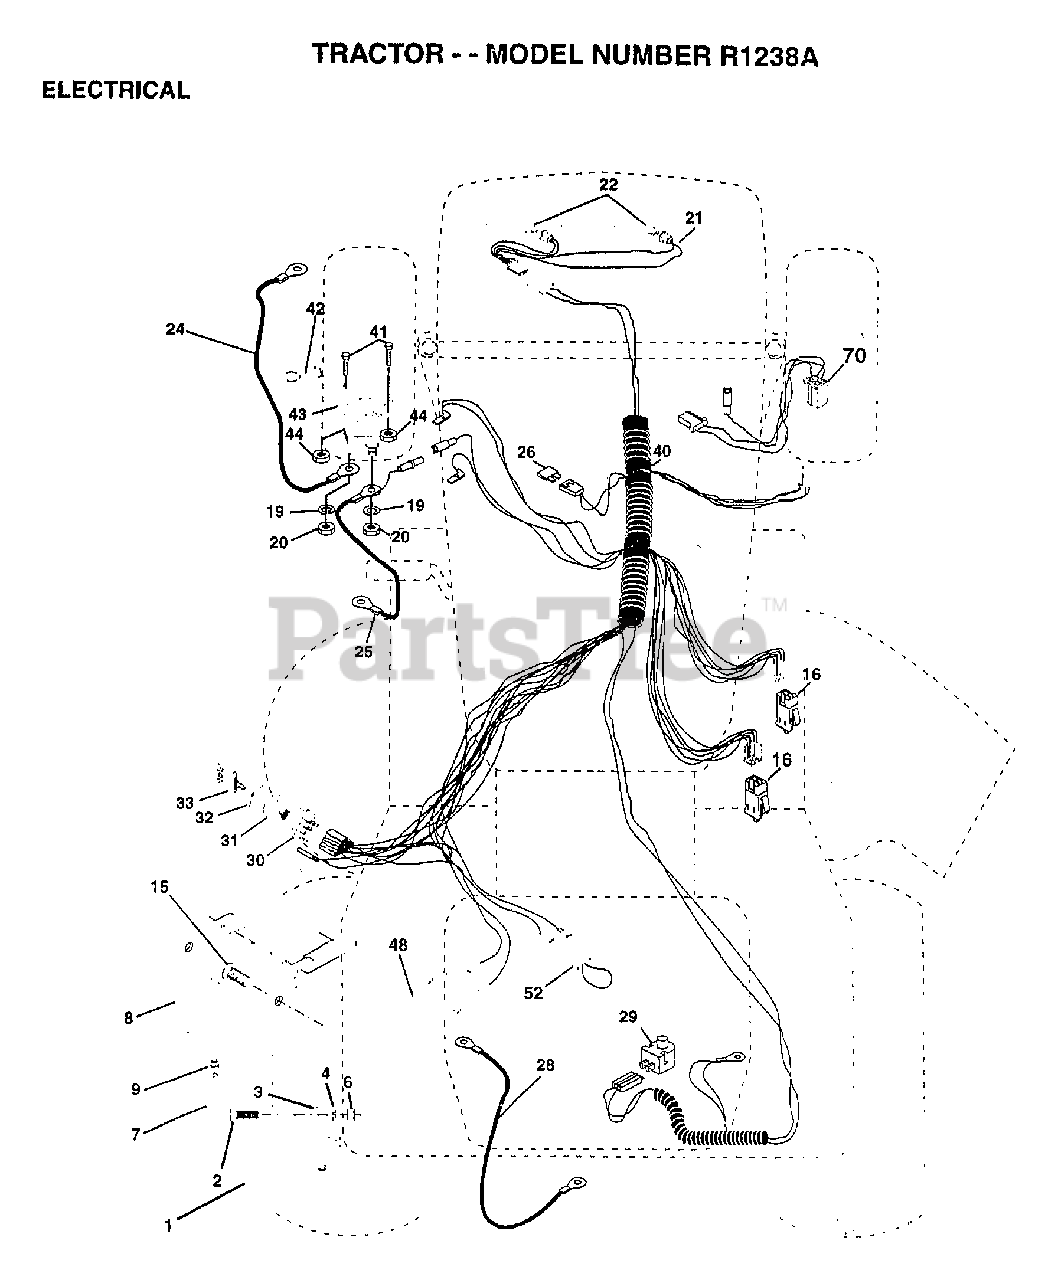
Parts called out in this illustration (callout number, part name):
2	BOLT LT
3	WASHER
4	LOCKWASHER
7	TUBE T
8	"CASE,BATTERY.MECH"
9	HOSE CLAMP T
15	FASTNER.SNAP-IN
16	SWITCH INTERLOCK
20	NUT
21	"HARNESS,LIGHT SOC"
22	HEADLAMP BULB
24	"CABLE T, BATTERY"
25	CABLE.BTRY.6GA.RD
26	FUSE HYT
28	CABLE T
29	SWITCH SEAT
30	SWITCH IGN 4POS
31	NUT IGNITION
32	COVER KEY SWITCH
33	KEY
40	HARNESS-IGNITION
41	BOLT HXHD FIN
44	NUT HXKEP 1/4X20
48	ADAPTER AMMETER
52	PROTECTION LOOP
70	HARNESS ENG DUAL
